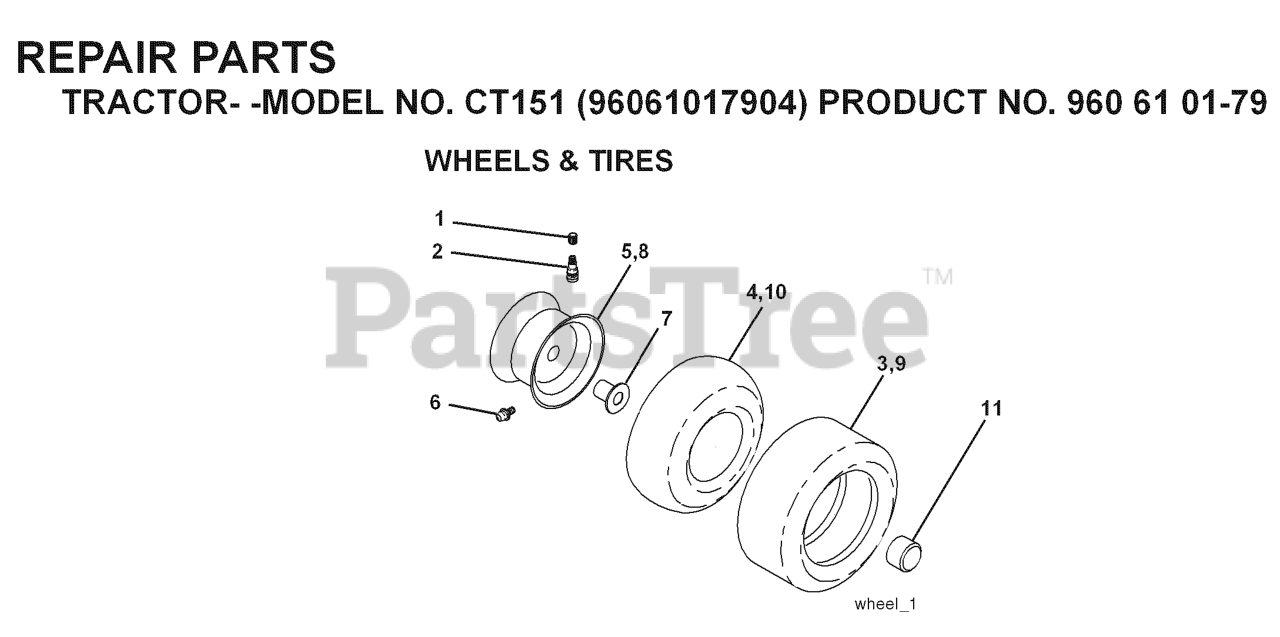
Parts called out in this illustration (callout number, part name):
2	VALVE STEM LT
3	TIRE HEAVY DUTY
4	TUBE.5.3/4.5/6
5	RIM ASM 6" FRONT SILVER
6	FITTING LT
7	BEARING T
8	RIM ASM 8" REAR SILVER
9	TIRE HEAVY DUTY
10	TUBE
11	CAP, AXLE BLK
